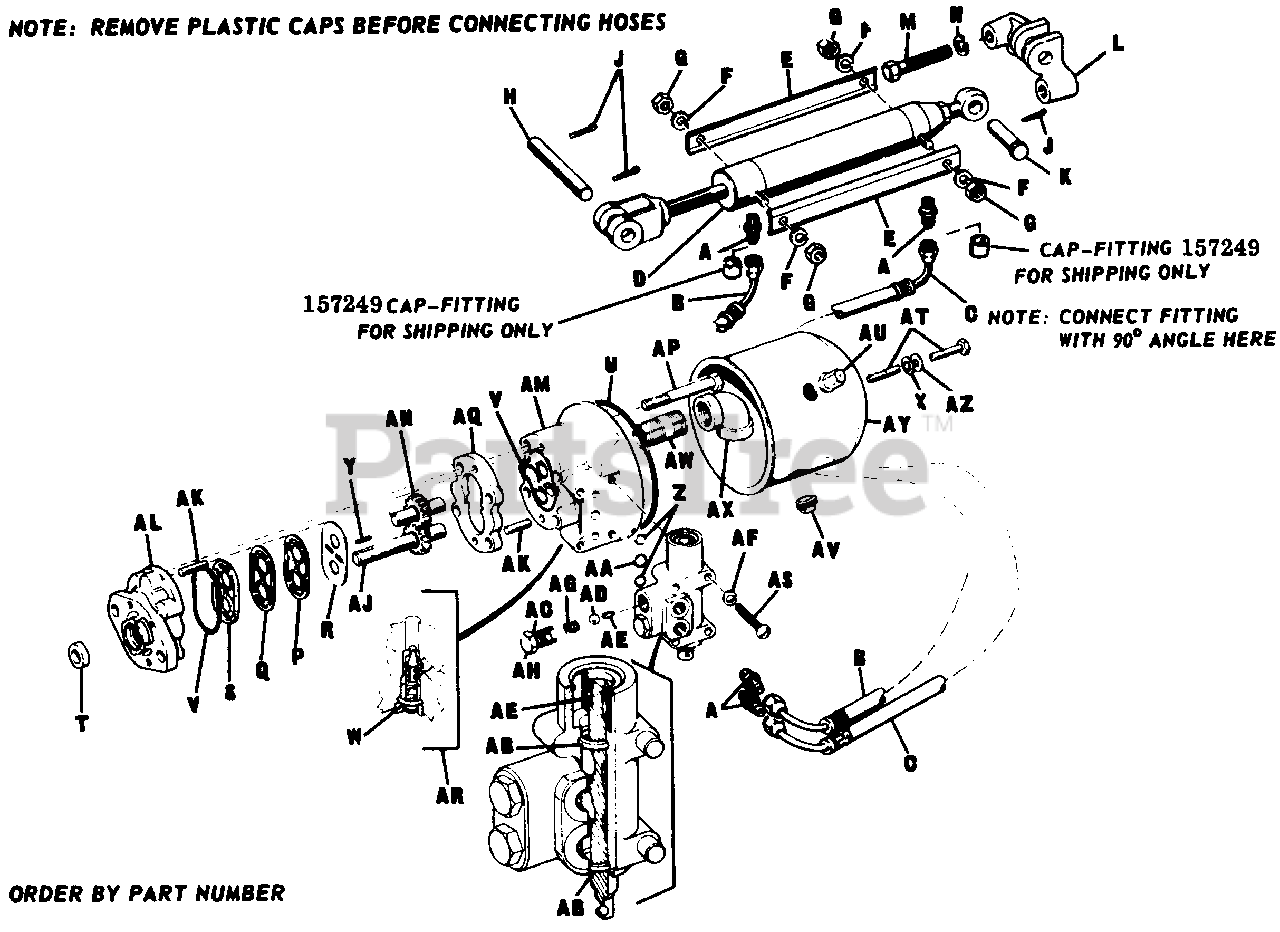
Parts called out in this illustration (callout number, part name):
B	Hose Assembly
C	Hose Assembly
D	Cylinder Assembly
F	Lock Washer, 5/16"
G	Full Hex. Nut, 5/16"-18
J	Cotter Pin, 1/8" x 3/4"
K	Ram Bracket Pin
L	Ram Bracket
M	Hex. Cap Screw 7/16"-14 x 2-1/4"
N	Lock Washer, 7/16"
P	Heat Shield (for service only)
R	Wear Plate
T	Rotary Seal
X	Stat-O-Seal
Y	Shaft Drive Key
AF	Lock Washer 1/4"
AJ	Drive Gear Assembly
AK	Dowel Pin
AL	Front Cover Assembly
AM	Back Cover Assembly
AN	Driven Gear Assembly
AQ	Center, Section Machined
AR	Relief Valve Assembly
AU	Filler Cap Plug
AV	Drain Plug
AW	Inlet Nipple
AX	Inlet Elbow
AY	Tank Assembly
AZ	Flat Washer, 1/4"
